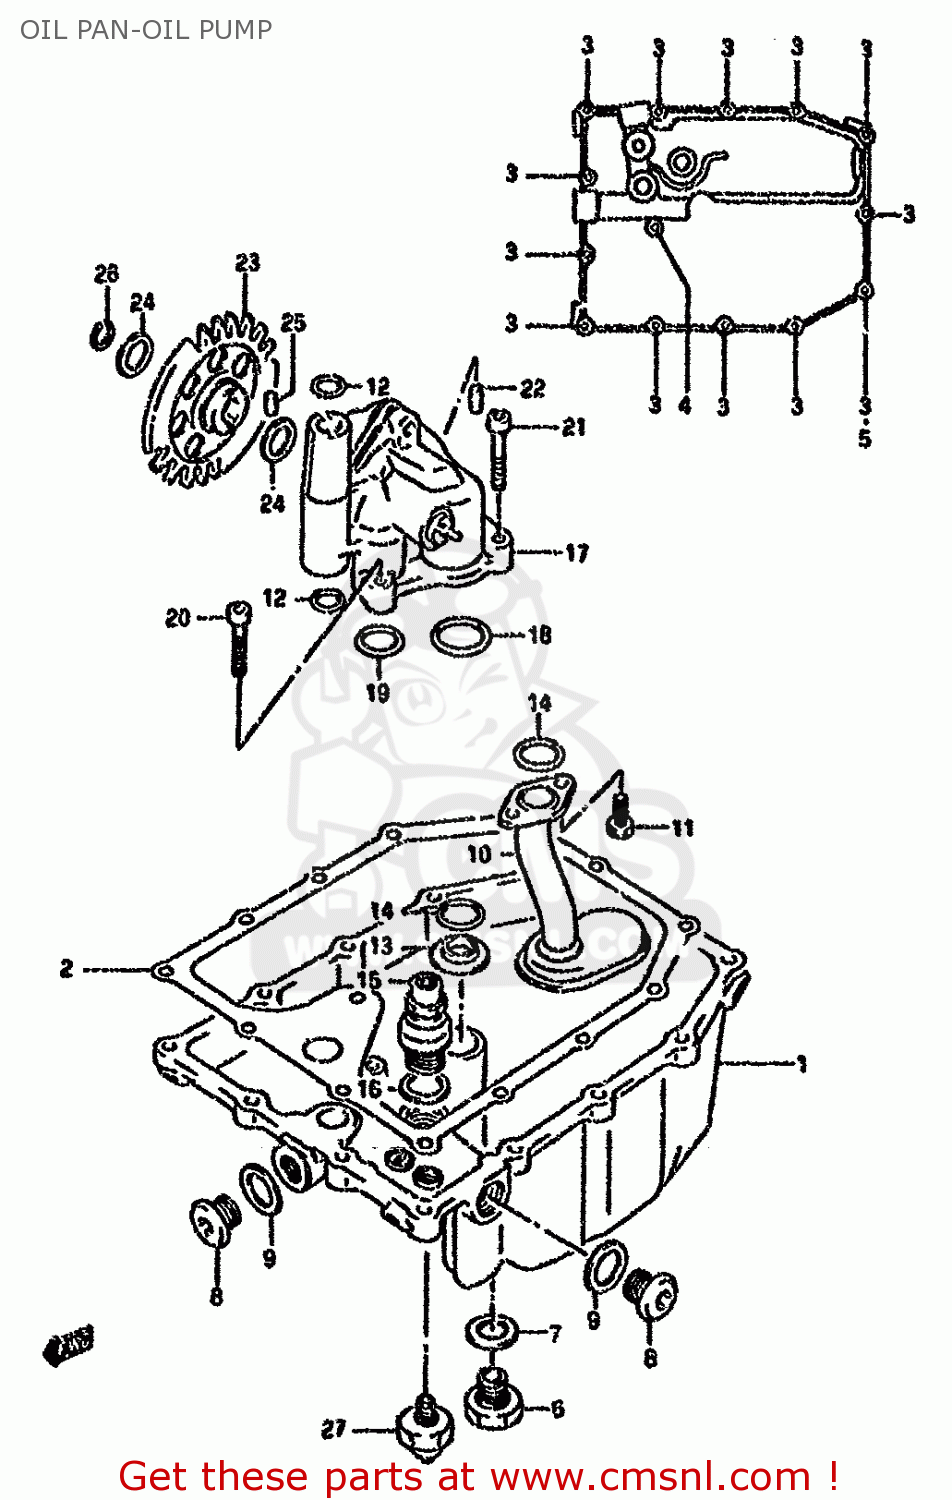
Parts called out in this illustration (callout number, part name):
1	PAN,OIL
2	GASKET,OIL PAN
3	BOLT
4	BOLT
5	GASKET(5.8X11X1.2) (NAS)
6	PLUG
7	GASKET(14X19.2X2) (NAS)
8	PLUG
9	GASKET(16X22X2) (NAS)
10	STRAINER COMP,ENGINE OIL
11	SCREW
12	O RING(D:2.4,ID:11.8)
13	GASKET,OIL OUTLET (NAS)
14	O RING(D:3.2,ID:17.8)
15	VALVE ASSEMBLY,OIL RELIEF
16	GASKET(16X22X2) (NAS)
17	PUMP ASSY,ENGINE OIL
18	O RING(D:2.4,ID:26.2)
19	O RING(D:3.2,ID:17.8)
20	BOLT
21	BOLT
22	PIN
23	GEAR,OIL PUMP DRIVEN(NT:37)
24	SHIM
25	PIN(5X18)
26	CIRCLIP,12 MM
27	SWITCH ASSEMBLY,OIL PRESSURE
